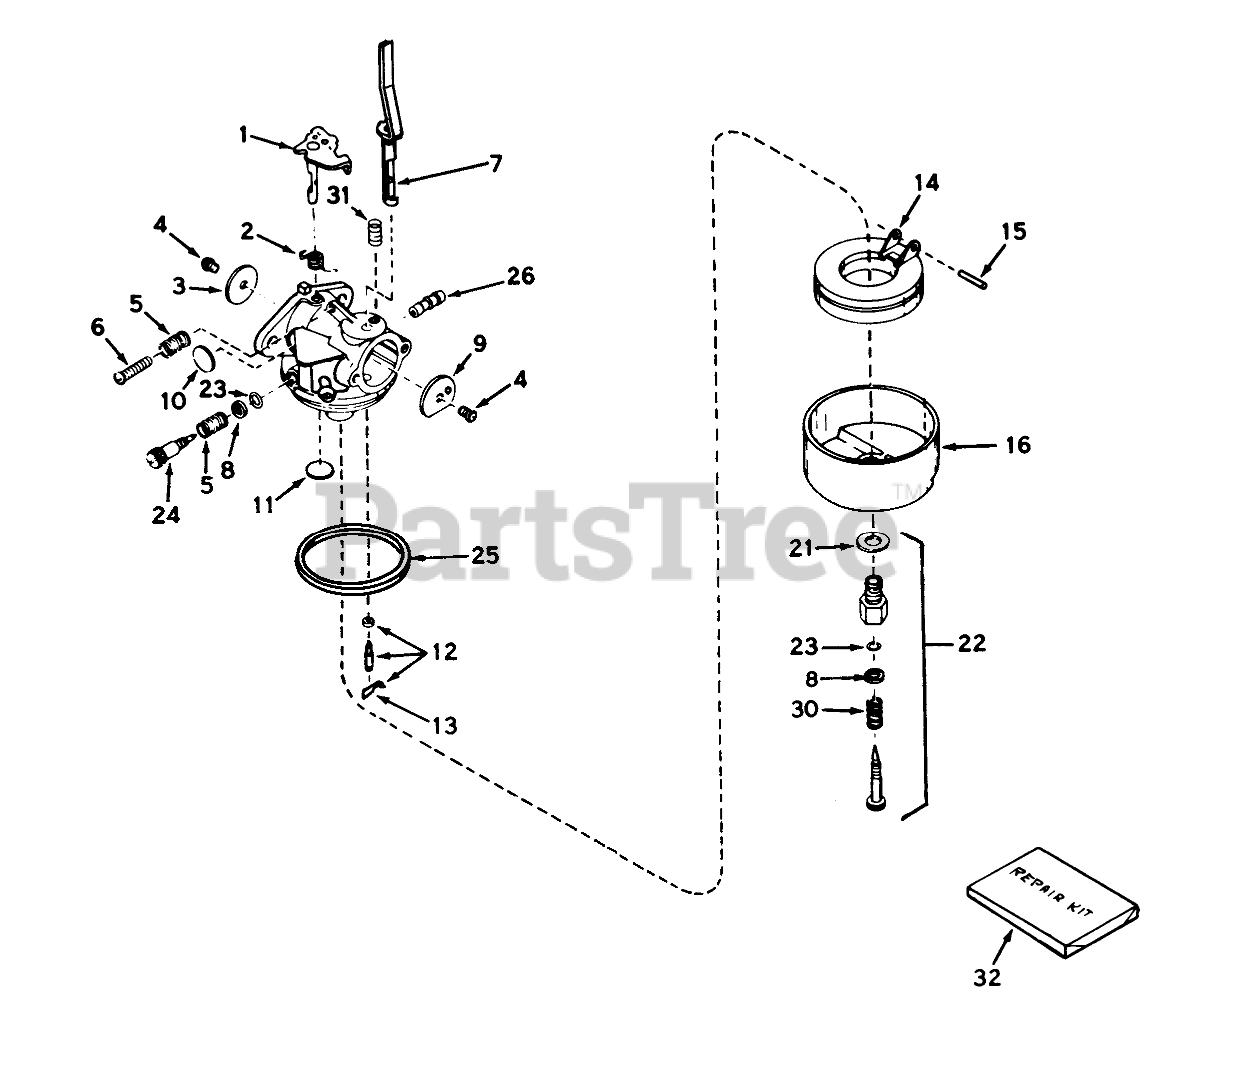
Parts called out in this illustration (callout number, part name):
1	Shaft/Lever-Throttle
2	Spring, Return
3	Shutter-Throttle
4	Screw-Shutter
5	Spring-Tension
6	Screw-Throttle Crack Screw / Idle Speed
7	Shaft & Lever Assy., Choke
9	Shutter-choke
10	Plug-Welch, Idle Mixture Well
11	Plug-Welch, Atmospheric Vent
12	Inlet Needle, Seat & Clip Assy. (Incl. Ref. #13)
13	Clip-Spring
14	Float
15	Shaft-Float
16	Bowl-Float (no drain)
21	Washer-Bowl Nut
22	Adjustment Screw Assy., Main (Incl. Ref. #8, 21, 23 & 30)
23	"O"Ring
24	Screw, Idle Adj.
25	O Ring-Bowl, Float
26	Fuel Fitting
31	Spring-Positioning, Choke
32	Kit-Repair
